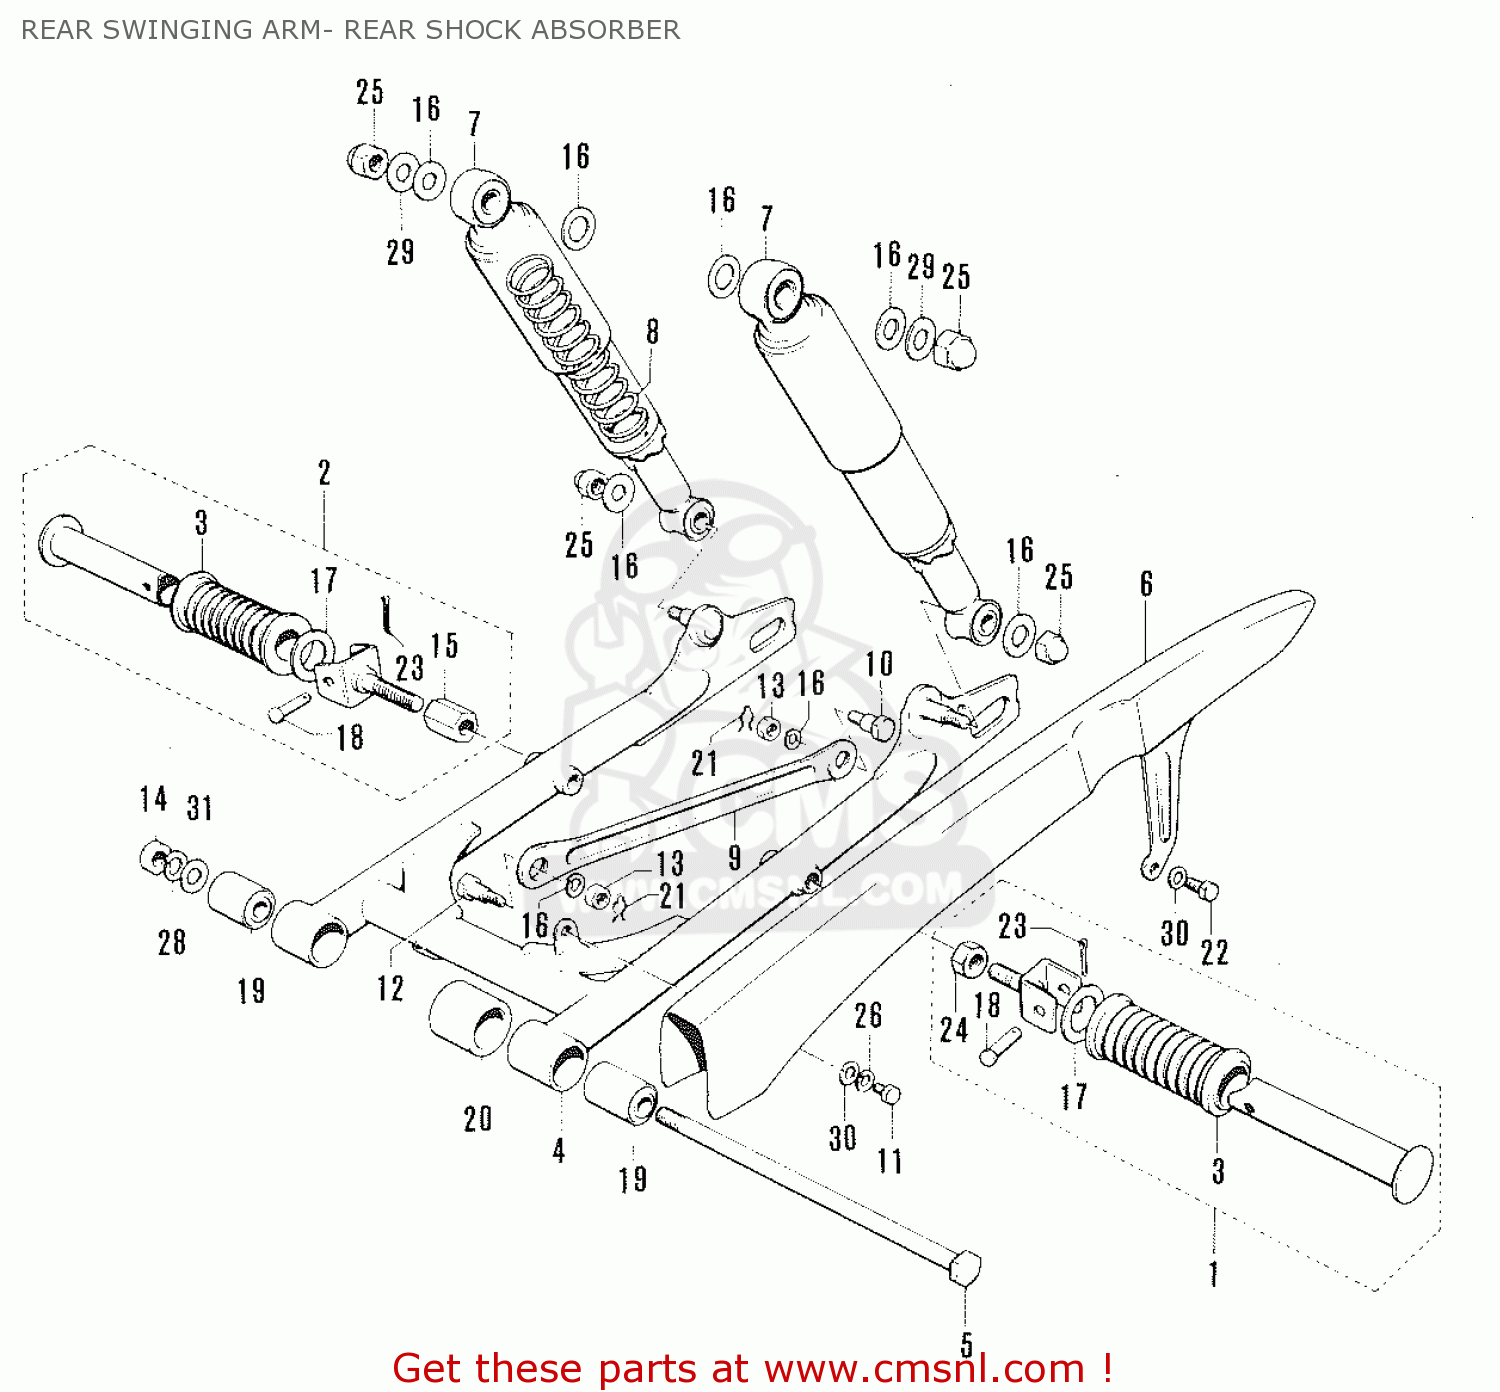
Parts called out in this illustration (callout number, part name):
1	FOOTREST ASSEMBLY,REAR
2	FOOTREST ASSEMBLY,PILLION
3	RUBBER,PILLION FOOTREST
4	SWING ARM ASSEMBLY,REAR
5	SHAFT,REAR SWING ARM
6	CHAIN CASE
7	ABSORBER ASSEMBLY,REAR SHOCK
8	SPRING
9	TORQUE LINK,REAR
10	BOLT,REAR TORGUE LINK,REAR
11	BOLT
12	BOLT, REAR TORQUE LINK
13	NUT
14	NUT
15	NUT
16	WASHER
17	WASHER (19.5X32X2)
18	PIN
19	BUSHING(10X23X35)
20	CUSHION
21	RETAINER,SNAP
22	HEXAGON BOLT
23	PIN
24	NUT
25	NUT
26	LOCK WASHER
27	LOCK WASHER
28	LOCK WASHER
29	WASHER
30	WASHER
31	WASHER
